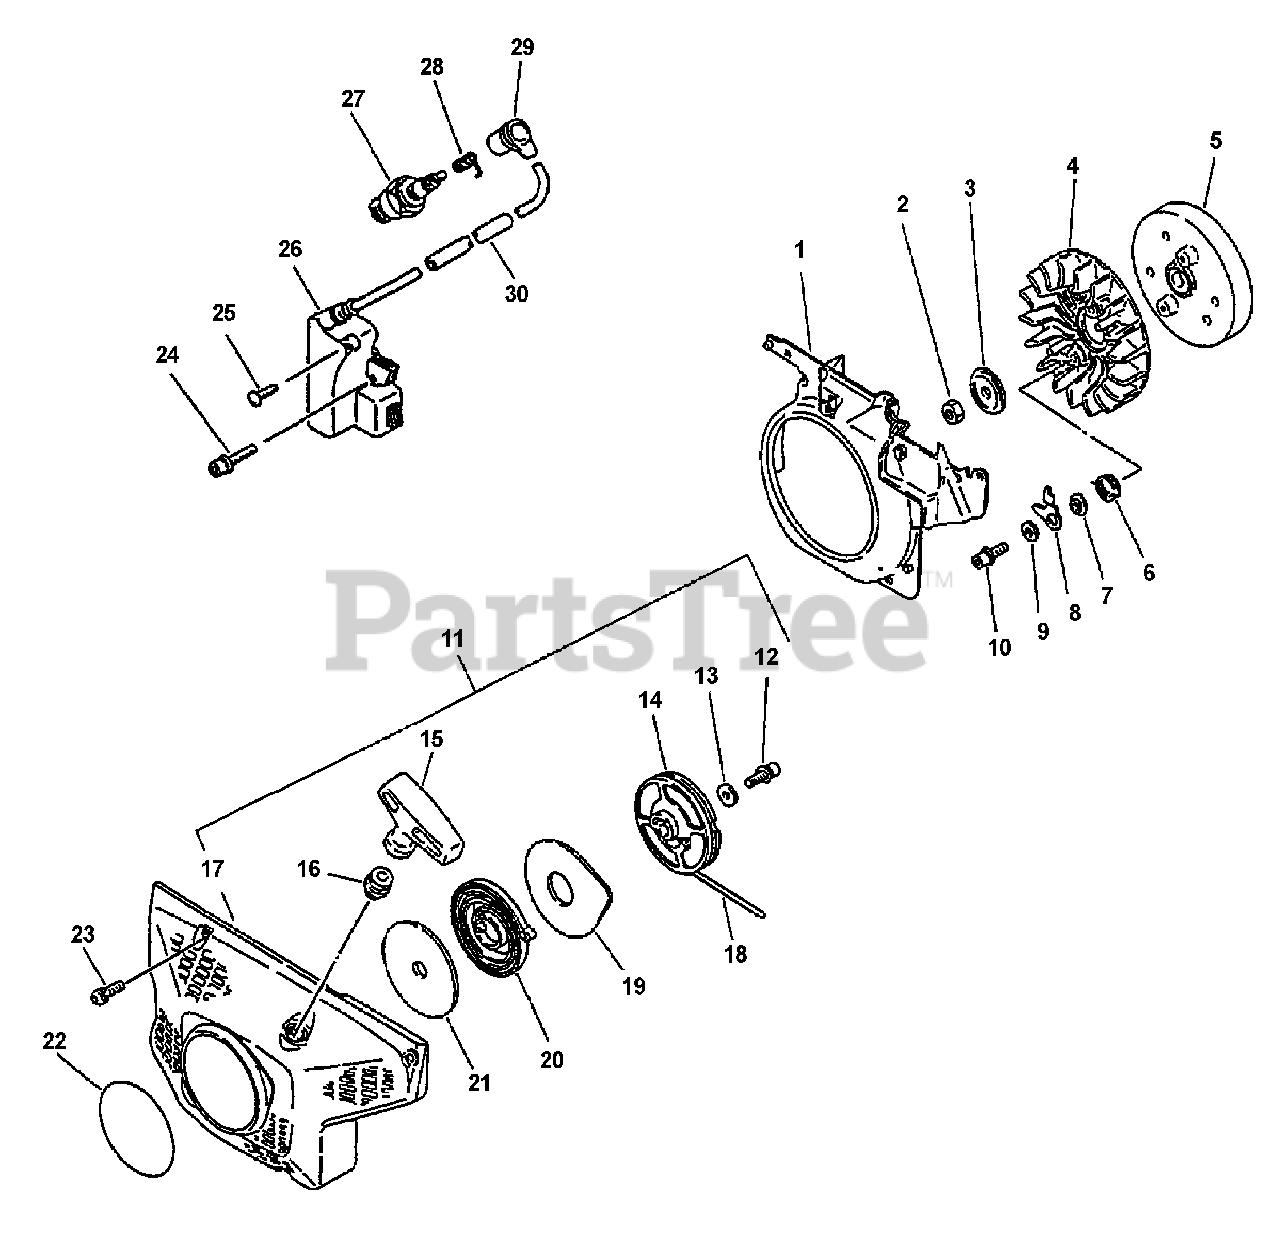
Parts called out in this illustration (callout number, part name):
1	SHIELD, FAN
3	WASHER 8.2×31×0.8
5	FLYWHEEL
6	SPRING, RETURN
7	SPACER, PAWL
8	PAWL, STARTER
9	WASHER 5.5×12×0.8
10	BOLT 5×14
11	STARTER ASSY
12	SCREW 5×14
13	WASHER 5.5×12×0.8
14	REEL, ROPE
15	GRIP, STARTER
16	GUIDE, ROPE
17	COVER, FAN
18	BULK STARTER ROPE - Ø 4.0 MM×61 M
19	PLATE, STARTER
20	SPRING, RECOIL
21	PLATE, STARTER
22	LABEL - ECHO
23	SCREW 5×20
24	BOLT 4×20
25	SCREW 4×8
26	COIL, IGNITION
27	SPARK PLUG - CJ-6Y
28	TERMINAL, SPARK PLUG
29	CAP, SPARK PLUG
30	TUBE
